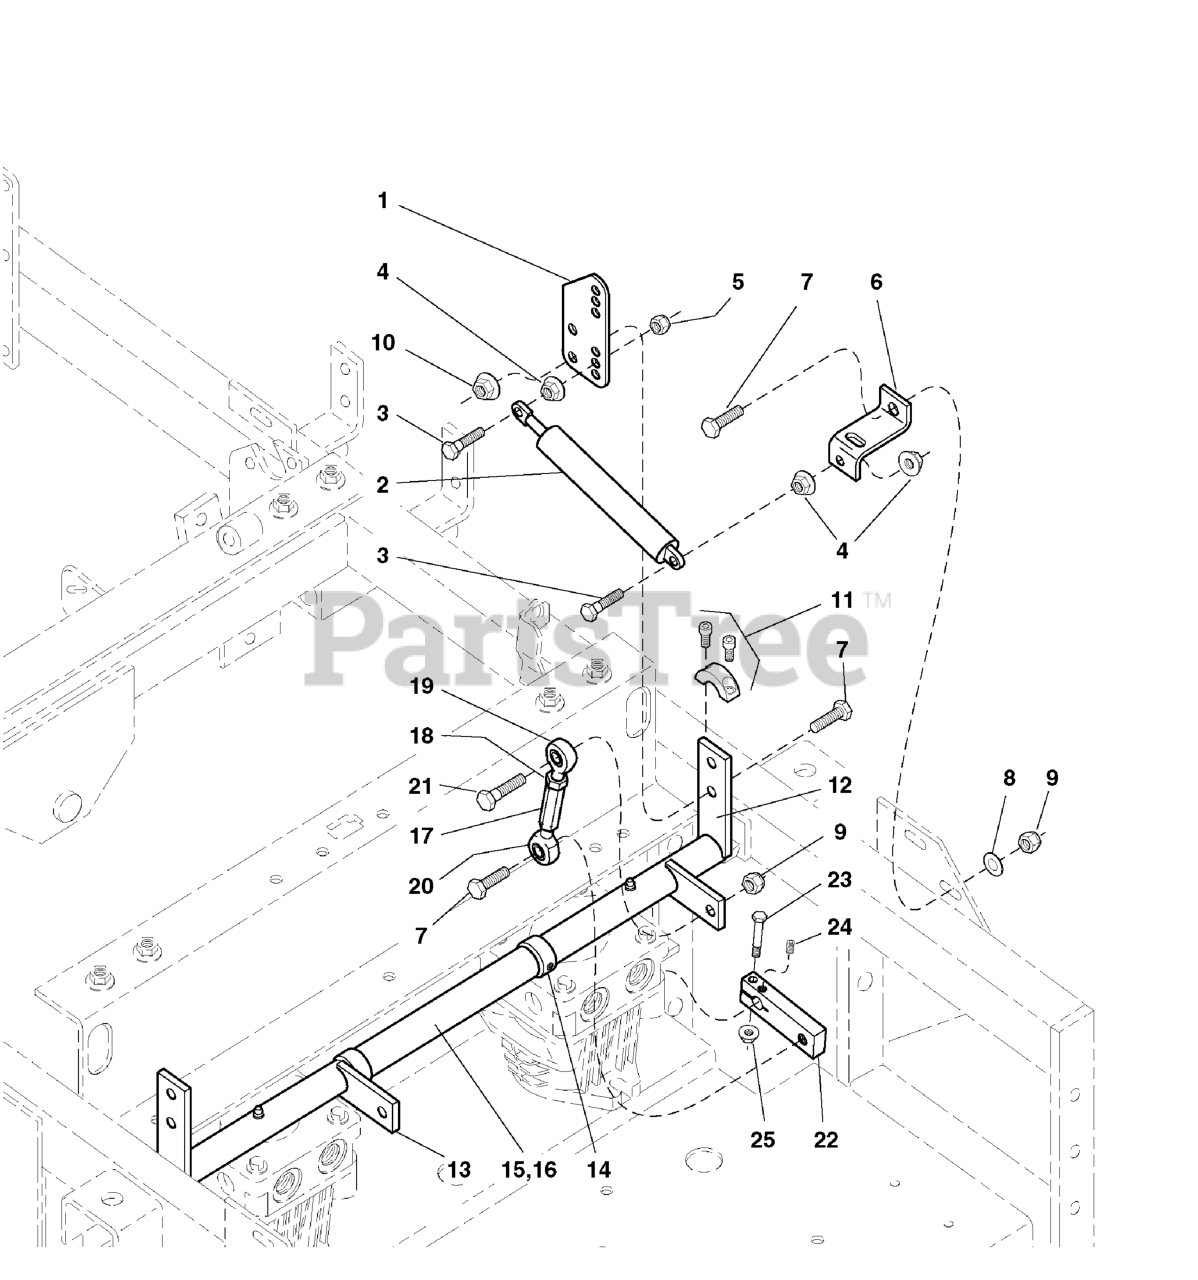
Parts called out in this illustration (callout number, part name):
1	DAMPENER MOUNT PLATE
2	DAMPENER
3	BOLT, 5/16-18 x 1-1/4
4	NUT, 5/16-18 HEX SERRATED FLANGE (SMALL)
5	NUT, 5/16-18 Hex Nylon Lock
6	DAMPENER MOUNT, Rear
7	BOLT, 3/8-16 X 1" GD5 CZ
8	WASHER, 3/8 SAE
9	NUT, 3/8-16 HEX NYLON LOCK
10	NUT, 3/8-16 Hex Serrated Flange
11	COLLAR, 3/4" Double Split
12	HYDRO CONTROL LEVER-RH
13	HYDRO CONTROL LEVER-LH
14	COLLAR, 3/4" Set
15	SHAFT, Control Pivot
16	COVER, Control Shaft
17	LINK, Control Arm
18	NUT, 3/8-24 Hex
19	BALL JOINT, 3/8-24 Male
20	BALL JOINT, 3/8-24 LH Male
21	BOLT, 3/8-16 X 1-1/4" GD5 CZ
22	ARM, Pump Control
23	BOLT, 1/4-20 X 1
24	SET SCREW, 1/4-20 x 3/8" Cone Point
25	NUT, 1/4-20 HEX SERR. FLANGE
